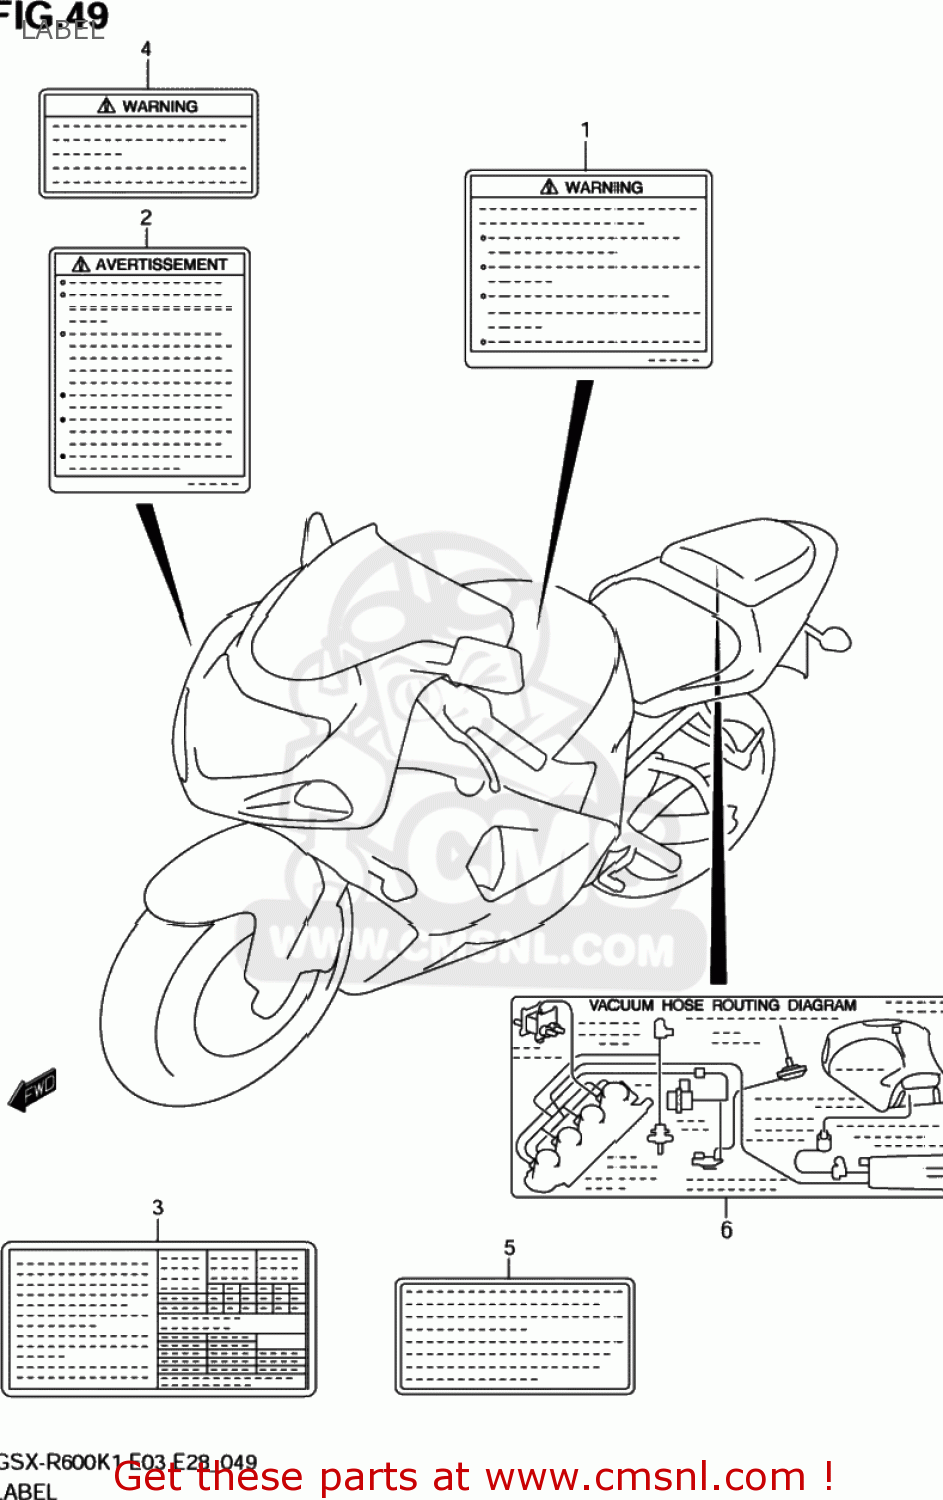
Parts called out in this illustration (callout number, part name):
1	LABEL,GENERAL WARNING
2	LABEL,SCREEN
3	LABEL,TIRE INFORMATION
4	LABEL,WARNING STEERING
5	LABEL,MANUAL NOTICE
6	LABEL,VACUUM HOSE ROUTING
7	MANUAL,OWNER'S
